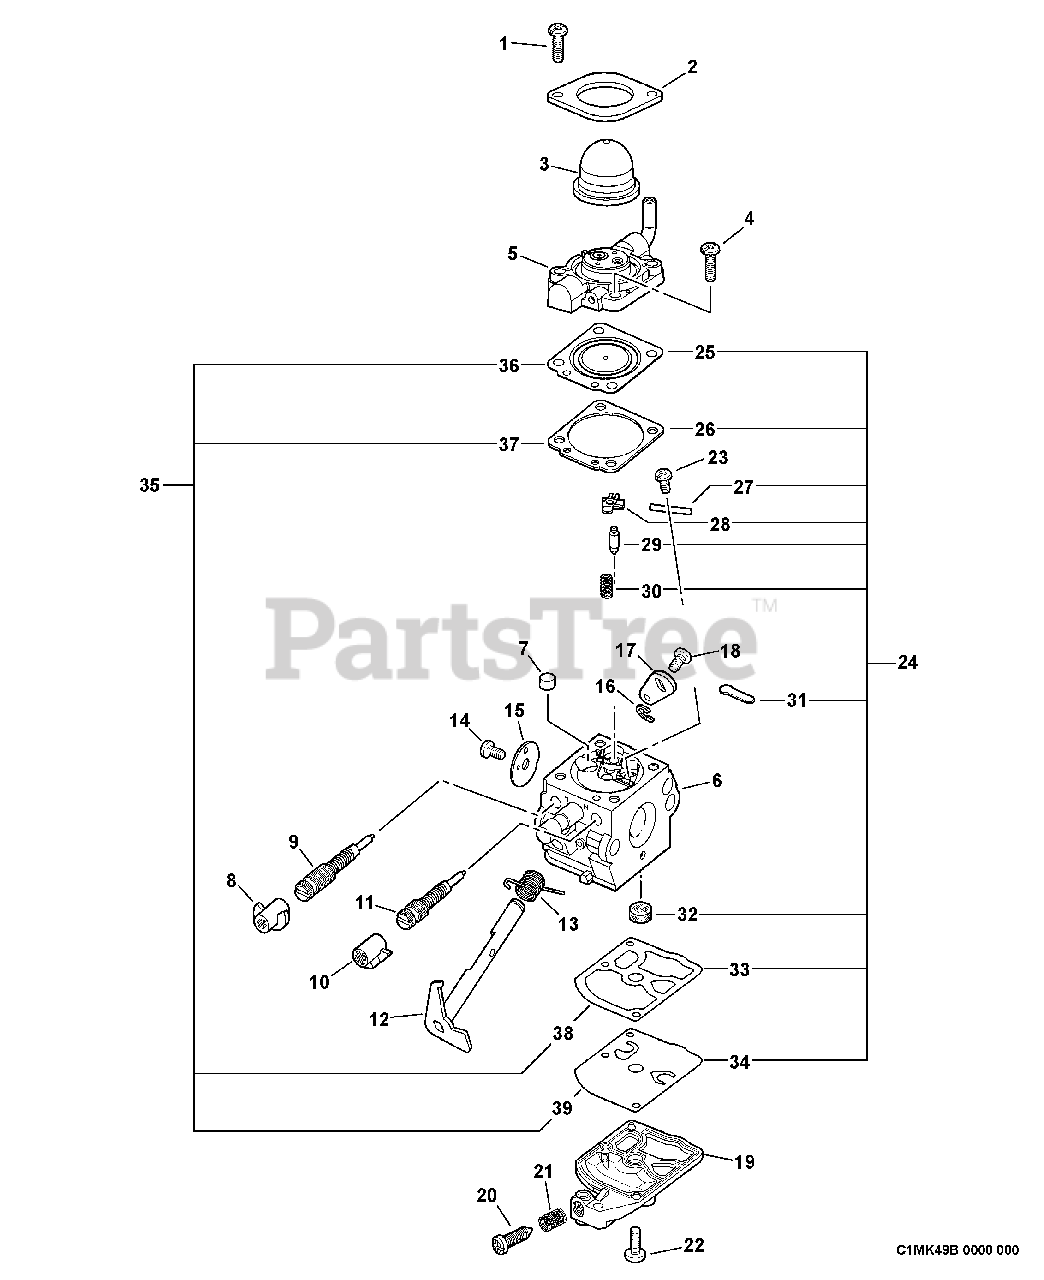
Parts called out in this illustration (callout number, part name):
2	RETAINER, PURGE BULB
3	BULB, PURGE
5	BODY ASSY, PURGE
6	BODY, CARBURETOR
7	NOZZLE, CHECK VALVE
8	CAP, LIMITER - WHITE
9	NEEDLE, LOW SPEED
10	CAP, LIMITER - RED
11	NEEDLE, HIGH SPEED
12	SHAFT, THROTTLE
13	SPRING, THROTTLE RETURN
15	VALVE, THROTTLE
17	LEVER, THROTTLE
19	COVER, PUMP
21	SPRING, IDLE ADJUST
24	REPAIR KIT
25	DIAPHRAGM, METERING
26	GASKET, DIAPHRAGM
27	PIN, METERING LEVER
28	LEVER, METERING
29	VALVE, INLET NEEDLE
30	SPRING, METERING LEVER
31	PLUG, WELCH
32	STRAINER
33	GASKET, PUMP
34	DIAPHRAGM, PUMP
35	GASKET / DIAPHRAGM KIT
36	DIAPHRAGM, METERING
37	GASKET, DIAPHRAGM
38	GASKET, PUMP
39	DIAPHRAGM, PUMP
